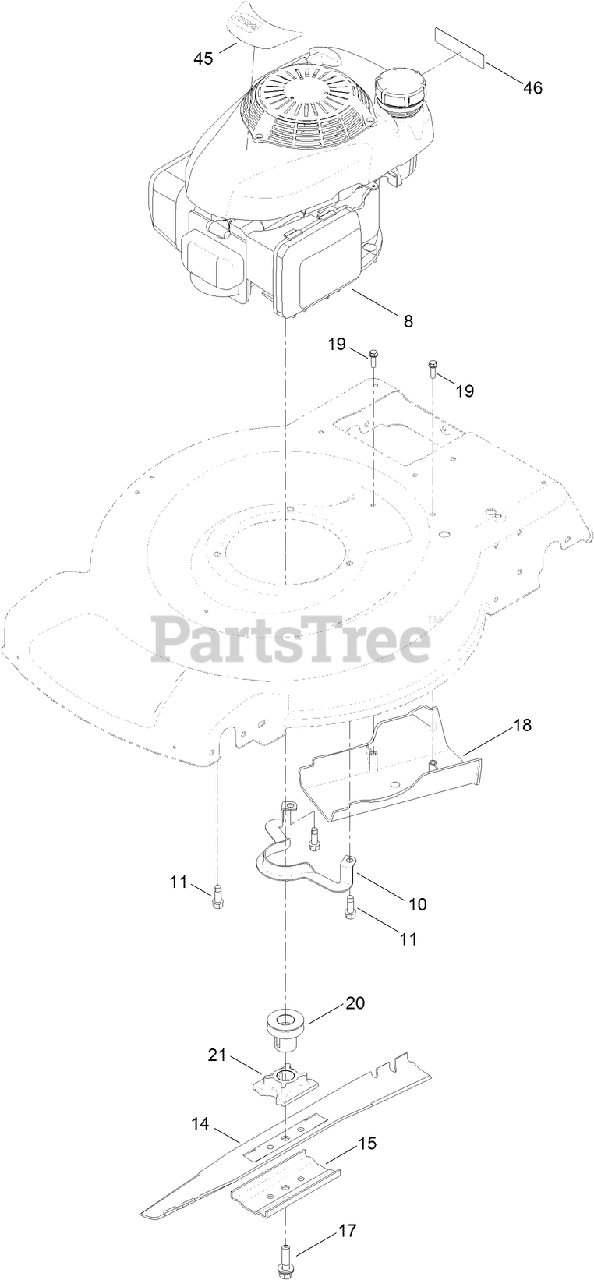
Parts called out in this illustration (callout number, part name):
10	GUIDE-BELT
11	SCREW-TAPTITE
14	BLADE-22 INCH
15	SUPPORT-BLADE
17	BOLT-BLADE
18	COVER-BELT
19	SCREW-HWH
20	PULLEY
21	RETAINER-BLADE
45	DECAL-SHROUD, HONDA
46	DECAL-ARRESTER, SPARK
